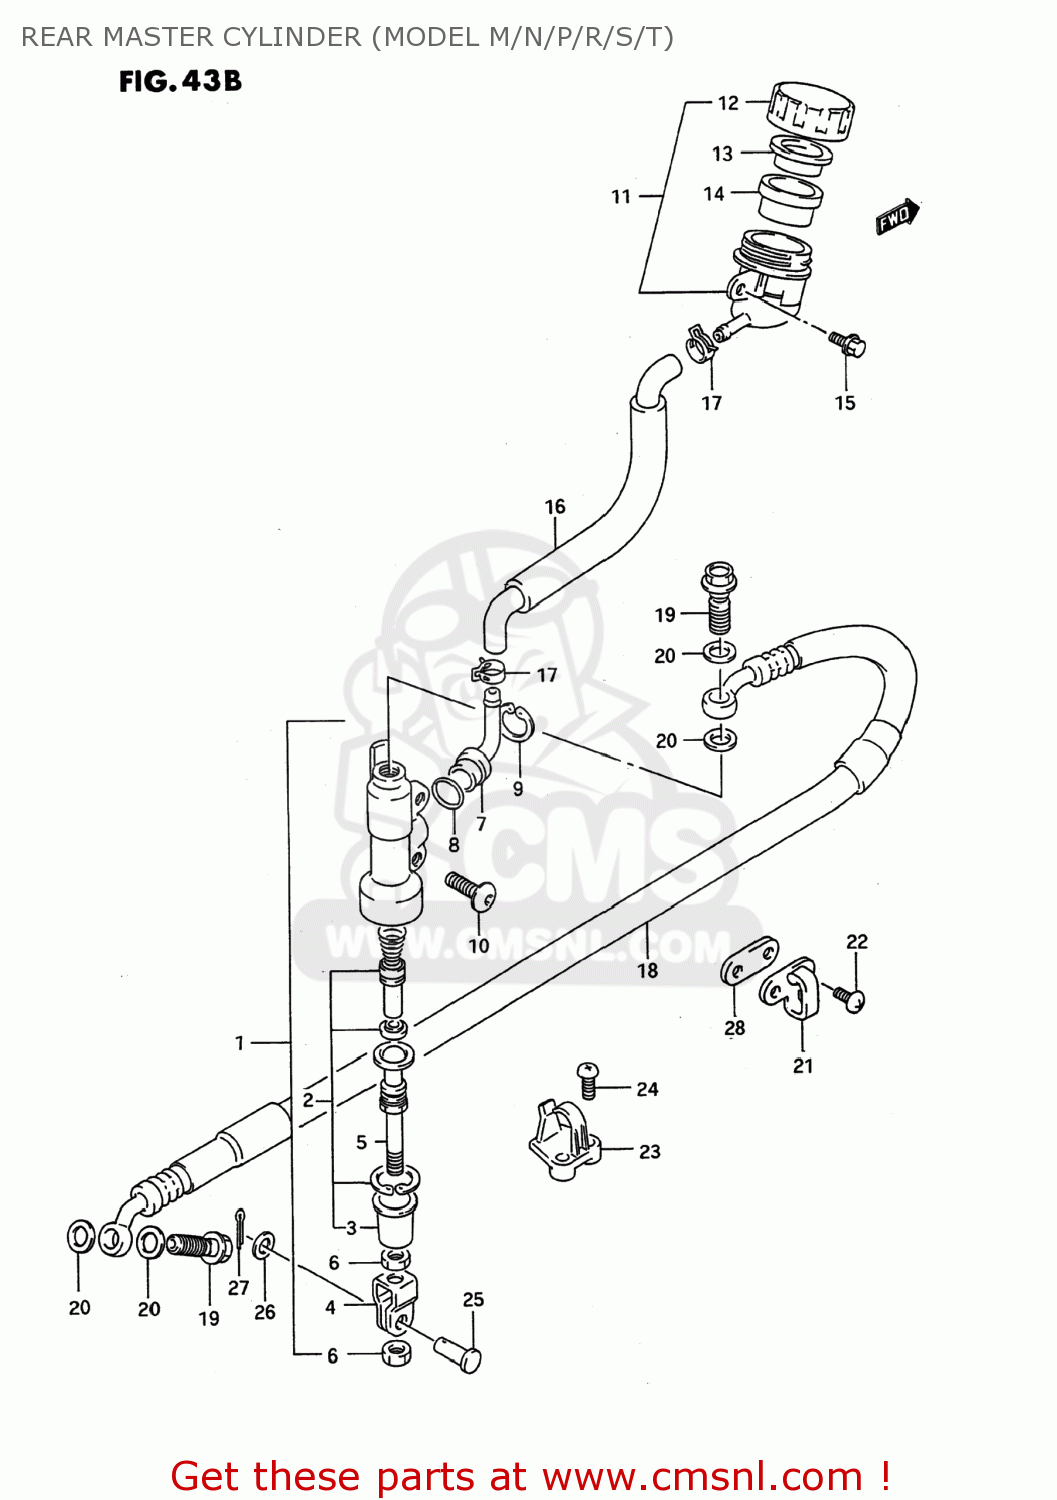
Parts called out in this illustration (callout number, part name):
1	CYLINDER ASSY,RR MASTER
2	PISTON/CUP SET
3	BOOT
4	YOKE
5	ROD,PUSH
6	NUT
7	CONNECTOR
8	O RING
9	CIRCLIP
10	SCREW(6X16)
11	TANK ASSY,RR BRAKE RESERVOIR
12	CAP
13	PLATE
14	DIAPHRAGM
15	BOLT
16	HOSE,TANK
17	CLAMP,RESERVOIR HOSE
18	HOSE,RR BRAKE
19	BOLT UNION
20	WASHER(10X15X1.5)
21	GUIDE,RR BRAKE HOSE
22	SCREW
23	GUIDE,RR BRAKE HOSE
24	SCREW
25	PIN(8X20)
26	WASHER(8.5X13X1.6)
27	PIN
28	SEAT,RR BRAKE HOSE GUIDE
